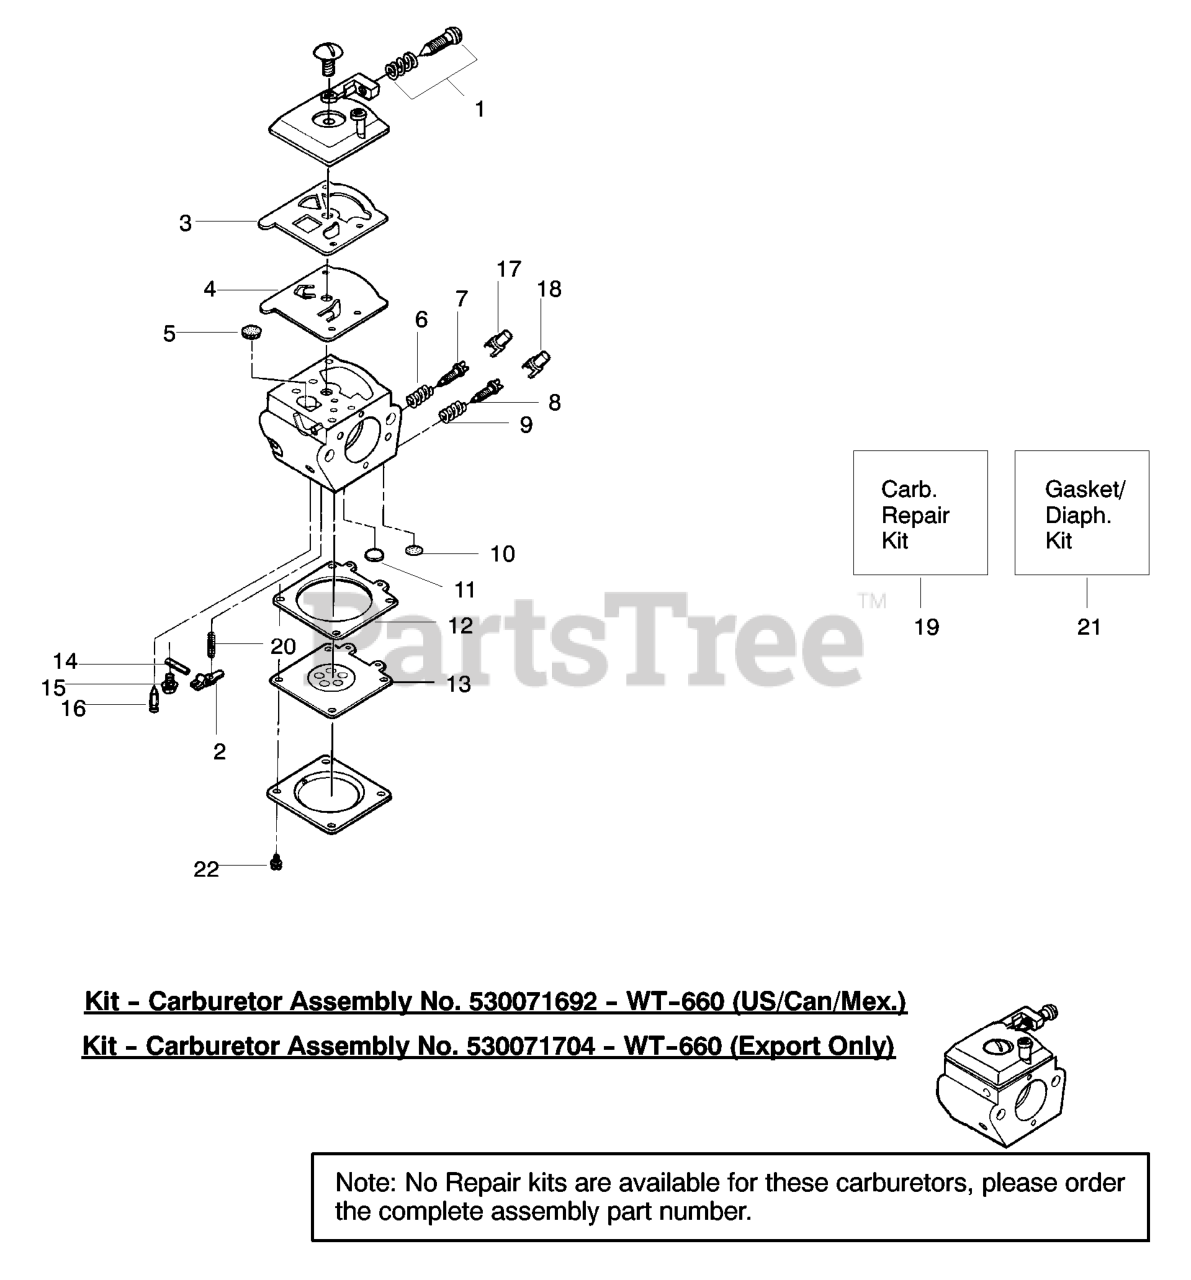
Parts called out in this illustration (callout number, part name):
1	IDLE ADV SCREW KIT
2	LEVER
3	GASKET-FUEL PUMP
4	DIAP FUEL PUMP
5	FILTER SCREEN
6	NEEDLE SPRING
7	LOW SPEED NEEDLE
8	High Speed Needle
9	NEEDLE SPRING
10	Welch Plug (5/16)
12	METERING DIA GASKET
13	DIAPHRAGM
14	PIN
16	INLET NEEDLEVALVE
17	LIMITER CAP-HIGH
18	LIMITER CAP-LOW
19	Carburetor Repair Kit
19	CARB REPAIR KIT
19	KIT, CARB REPAIR
20	SPRING-METERING LEVER
21	Gasket/Diaphragm Kit
21	GASKET/DIAPHRAGM KIT
21	GASKET/DIAPHRAGM KIT ZAMA
22	SCREW, MOTOR COVER
530071692	CARB WT-660
530071704	CARBURETOR
